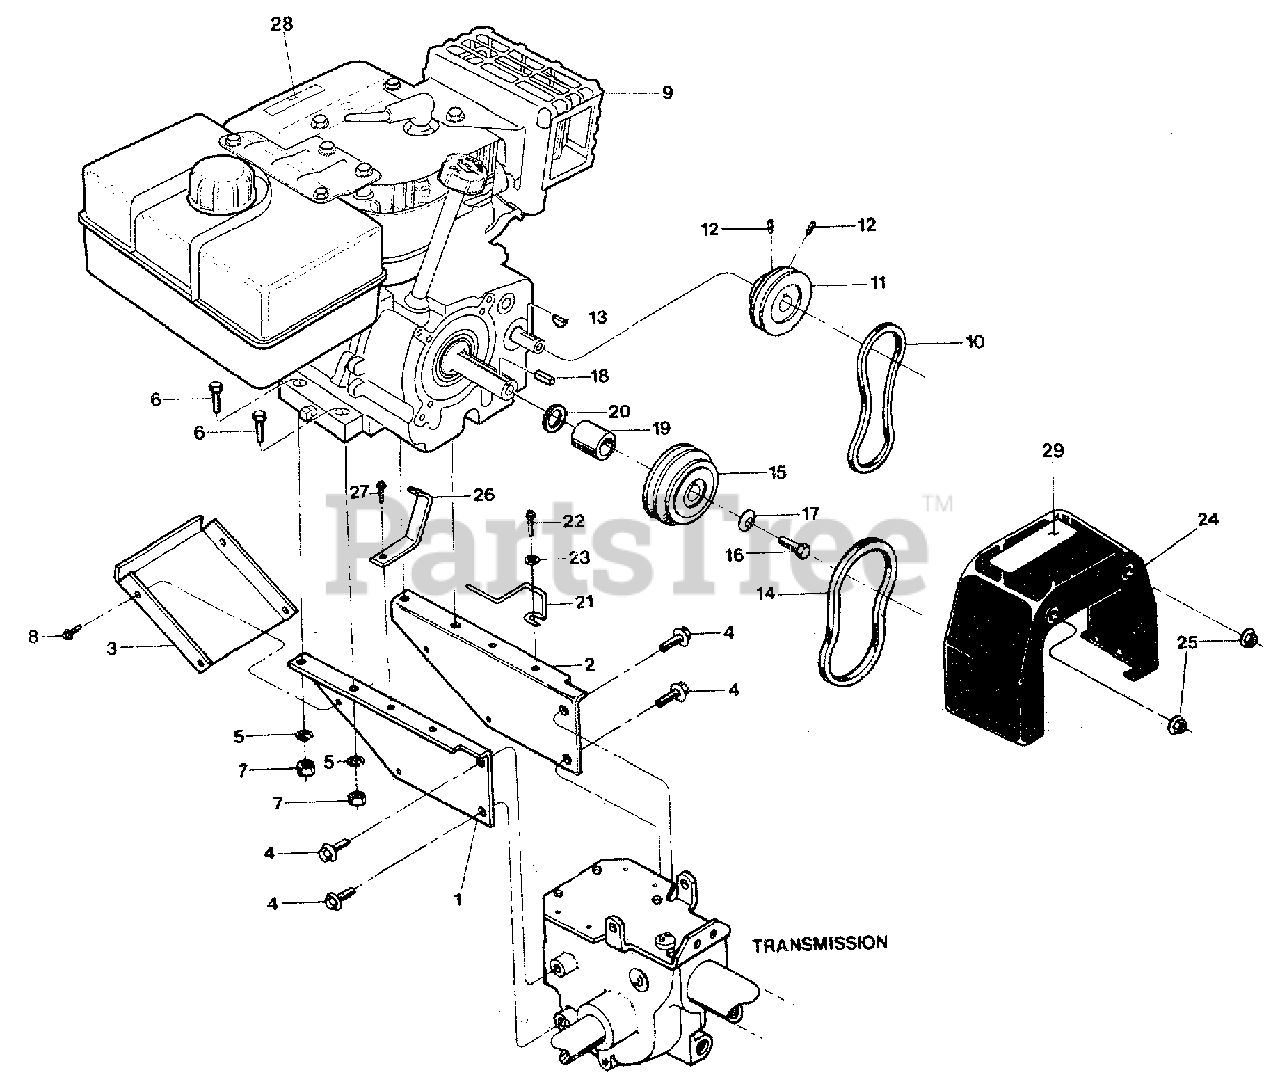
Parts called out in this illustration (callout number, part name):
1	Support Bracket-engine, left side
2	Support Bracket-engine, right side
3	Support Bracket (Pan)-engine, front
4	Screw-flanged hex hd., 5/16-18 x 3/4
5	Lockwasher-5/16
6	Screw-hex hd , 5/16-18 x 1-1/2
7	Nut-hex, 5/16-18
8	Screw-hex hd., 10-32 x 1/2, self-tapping
9	Engine
10	Flat Belt-reverse drive
11	Reverse Pulley-engine driven, for flat belt (Ref No 10)
12	Set Screw-Socket Head, 1/4-20 x 1/4
13	Key-Woodruff (size #5)
14	V-Belt-forward drive
15	Forward Pulley-engine drive, for V-Belt (Ref. No. 14)
16	Screw-hex hd., 5/16-24 x 3/4
17	Washer-disc spring (concave surface faces forward pulley)
18	Key-3/16 sq. x 1
19	Spacer
20	Shim
21	Belt Guide-forward drive belt
22	Screw-hex hd., self-tapping, 1/4-20 x 3/4
23	Washer-plain (flat), 1/4, S.A.E.
24	Cover
25	Nut-5/16-18, locking, whiz-style
26	Belt Guide-reverse drive belt
27	Screw-flanged hex hd., self-tapping, 1/4-20 x 1/2
28	Decal-Stabilization
29	Decal-Hot surfaces/belt warning
